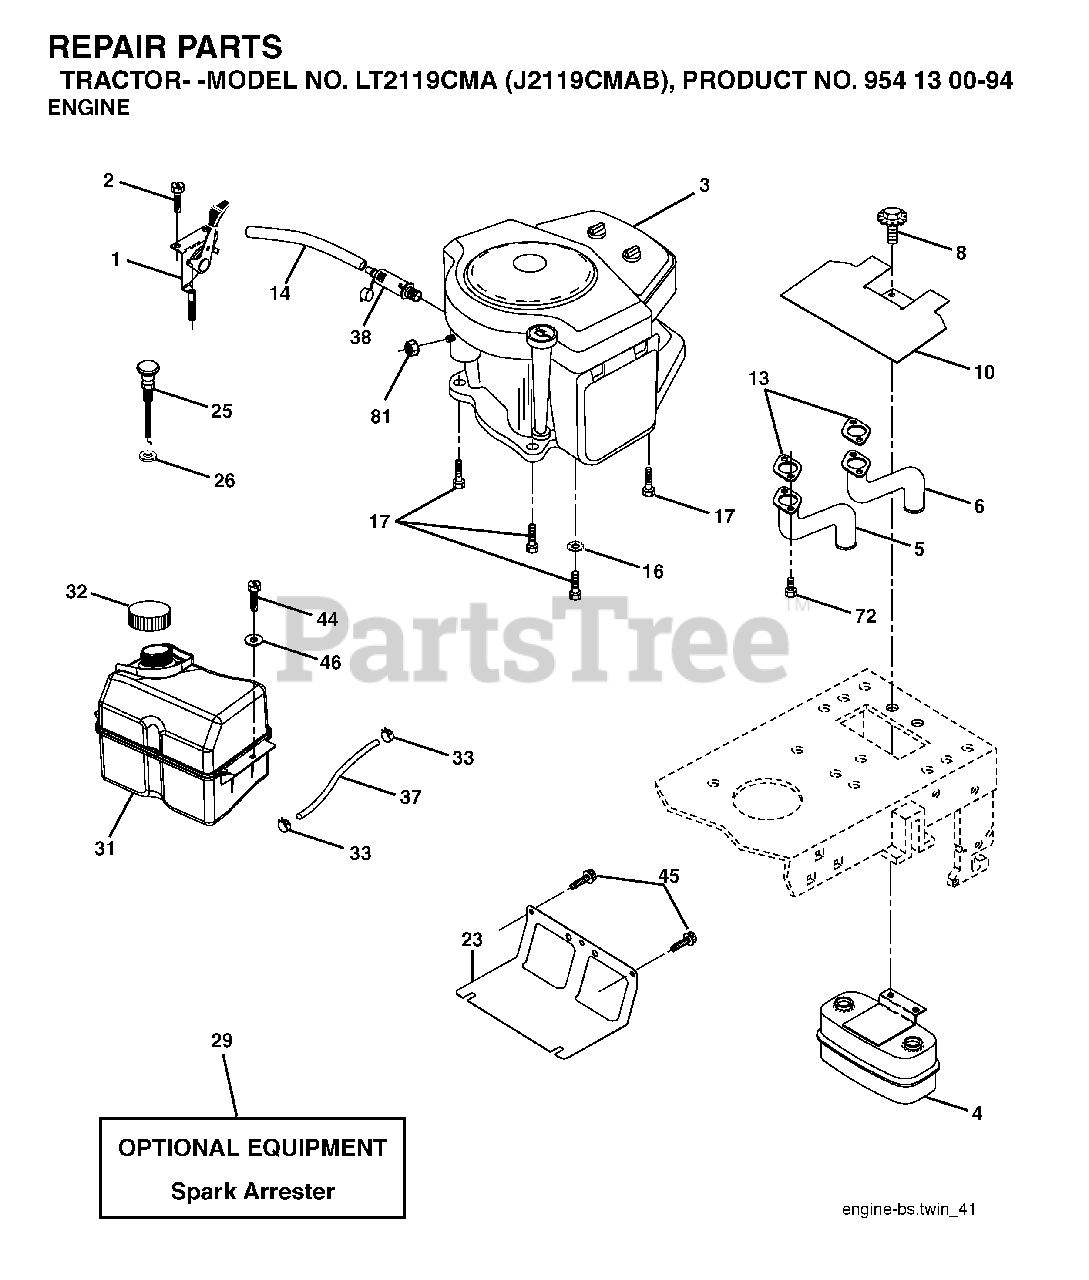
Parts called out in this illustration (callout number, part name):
1	THROTTLE CABLE
2	SCREW
4	MUFFLER.TWIN.CYL.LOW.TONE
5	TUBE MANIFOLD LH
6	EXHAUST TUBE RH
8	BOLT, 5/16-18 X 1 3/4
10	SHIELD.BROWNING.B&S
13	GASKET.MUFFLER
14	TUBE, DRAIN OIL ASM.
16	LOCKWASHER
23	SHEILD.BROWNING.DBR.GUARD
25	REPL BY 532 1754-40
26	NUT KEPS 3/8 - 24 UNF
29	ARRESTER SPARK (OPTIONAL)
31	TANK FUEL
32	FUEL CAP
33	HOSE CLAMP
37	LINE.FUEL.20
38	PLUG DRAIN OIL EASY
44	SCREW HEXWSHR 1/4-20X3/4
45	SCREW, 3/8-16X3/4
72	SCREW.SOCKET.HEAD.5/16-18
81	NUT
112	BUSHING OUTLET T
